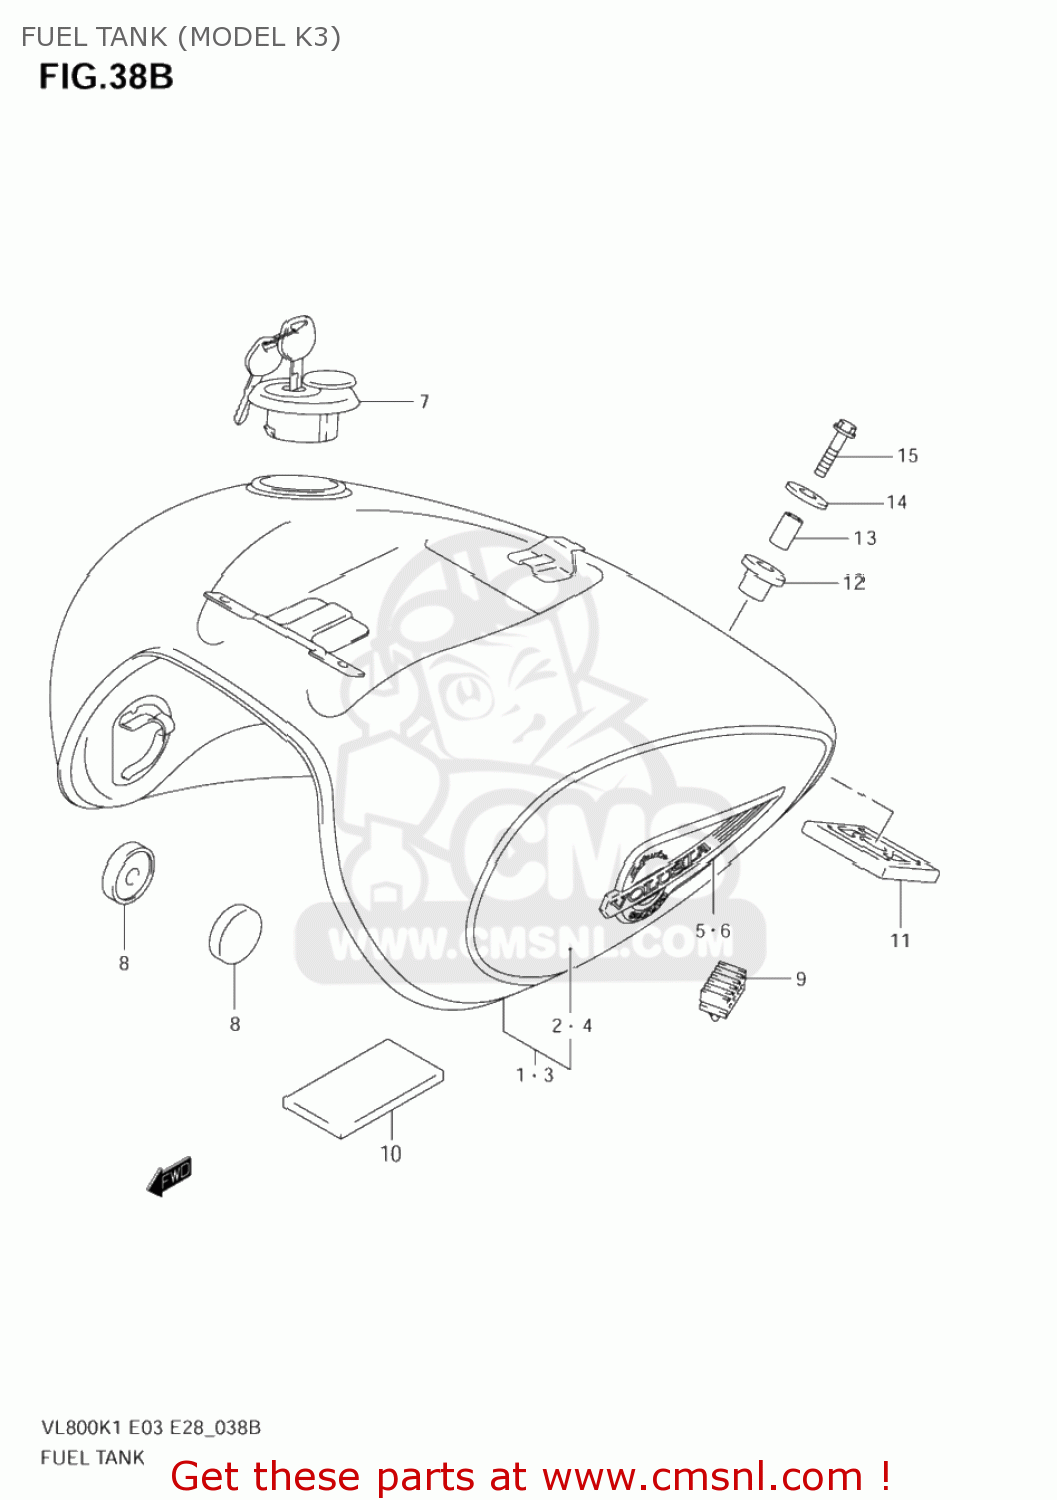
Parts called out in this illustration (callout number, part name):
1	TANK ASSY,FUEL(BLACK)
2	TAPE SET,FUEL TANK
3	TANK ASSY,FUEL
4	TAPE SET,FUEL TANK
5	EMBLEM,FUEL TANK,R
6	EMBLEM,FUEL TANK,L
7	CAP SET,FUEL TANK
8	CUSHION
9	CUSHION,SEAT(40X20X15)
10	CUSHION,FUEL TANK
11	CUSHION,FUEL TANK RR LWR
12	CUSHION,FUEL T
13	SPACER (8.2X12.5X23.5)
14	WASHER (8.5X33X1.6)
15	BOLT
